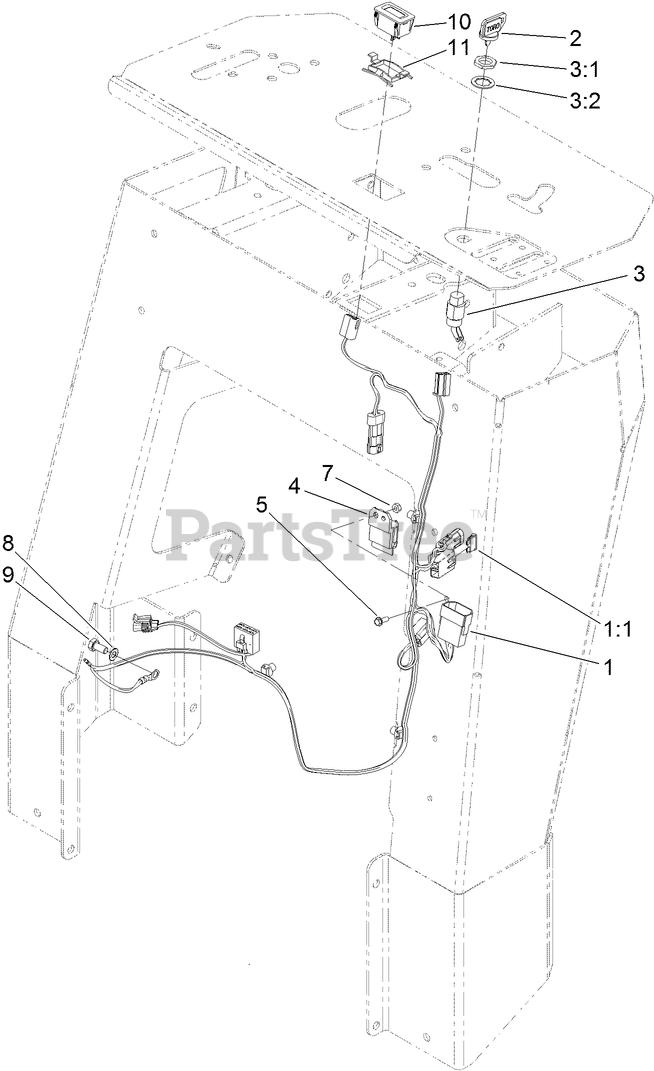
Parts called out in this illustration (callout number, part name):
1	HARNESS-WIRE
1:1	FUSE-BLADE, 15 AMP
2	KEY-IGNITION
3	SWITCH-ON / OFF
3:1	NUT-HH
3:2	WASHER-TOOTH, INTERNAL
4	MODULE-INTERLOCK
7	NUT-LOCK, NI
8	WASHER-LOCK
9	SCREW-HH
10	HOURMETER
11	CLIP-MOUNTING
